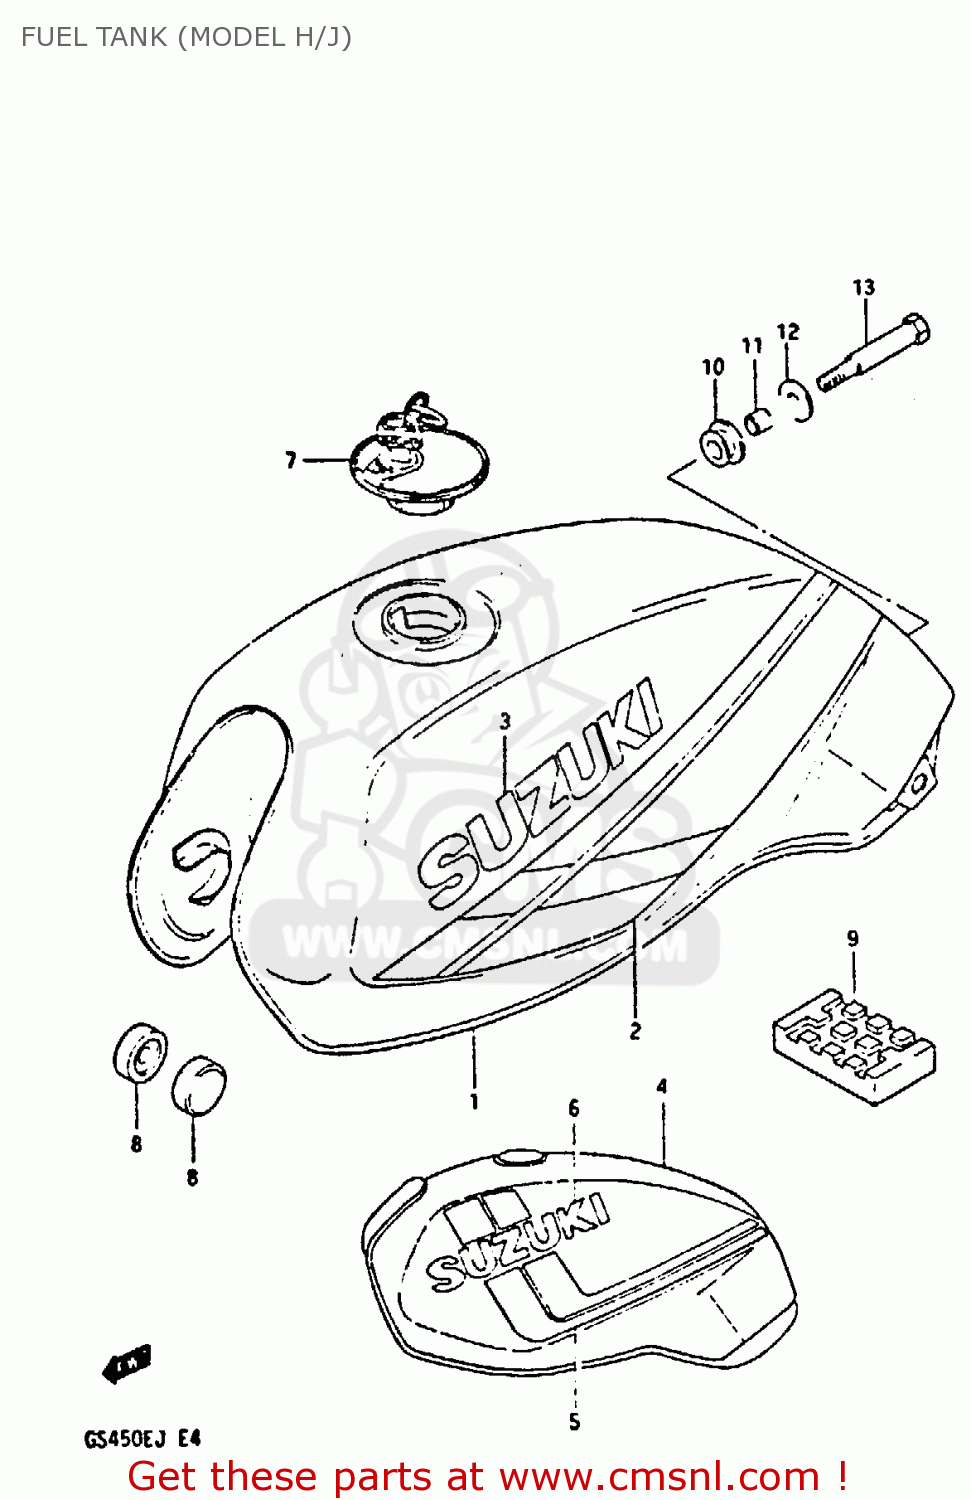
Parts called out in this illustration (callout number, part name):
1	TANK ASSY, FUEL (RED)
2	TAPE SET, FUEL TANK
3	EMBLEM, SIDE
4	TANK ASSY, FUEL (BLACK)
5	TAPE SET, FUEL TANK
6	EMBLEM
7	CAP SET,FUEL TANK
8	CUSHION
9	CUSHION,FUEL TANK CTR
10	CUSHION
11	SPACER (6.8X10X10)
12	WASHER (6.5X29X1.6)
13	BOLT(6X60)
